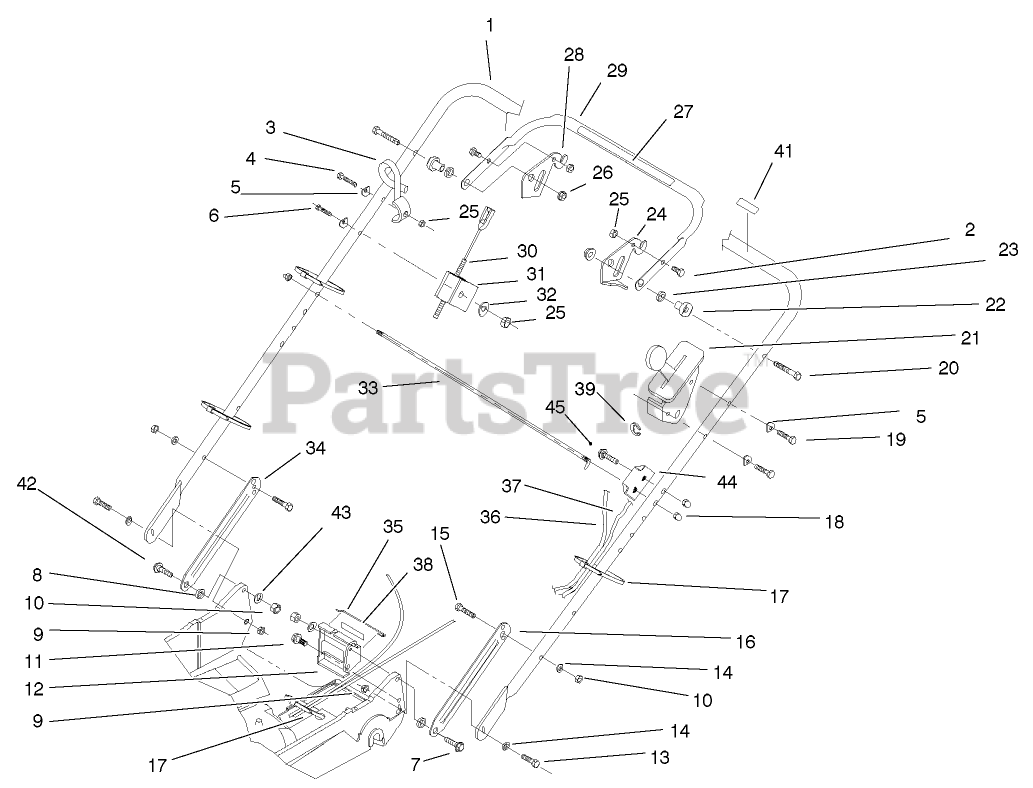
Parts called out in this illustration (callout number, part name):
2	SCREW-HH
3	GUIDE-ROPE
4	SCREW-HH
5	WASHER
6	SCREW-HH
7	SCREW-SHOULDER
8	SPACER
9	NUT-LOCK, NI
10	NUT-LOCK, NI
11	SCREW-HWHTF
12	BRACKET-ADJUSTMENT, TRACTION
13	SCREW-HH
14	WASHER-BELLEVILLE
15	SCREW-HH
16	LATCH-HANDLE, LH
17	TIE-CABLE
18	NUT-CAP
19	SCREW-HH
20	SCREW-HH
21	BRACKET-CONTROL, THROTTLE
22	SPACER-SUPPORT
23	SPACER-NYLON
24	LEVER-CONTROL
25	NUT-LOCK, NI
26	NUT-LOCK, NI
28	LEVER-CONTROL
29	BAR-CONTROL
30	CABLE-BRAKE
31	SUPPORT-CABLE
32	WASHER-FLAT
33	ROD-SUPPORT, BAG
34	LATCH-HANDLE, RH
35	RETAINER-CABLE
36	CABLE-TRACTION
38	DECAL-POSITION, GEAR
39	E-RING
41	DECAL-PROTECTION, EAR
42	SCREW-SHOULDER
43	WASHER-PLAIN
44	PLATE-ALIGNING, BAG
45	SCREW-CARR
